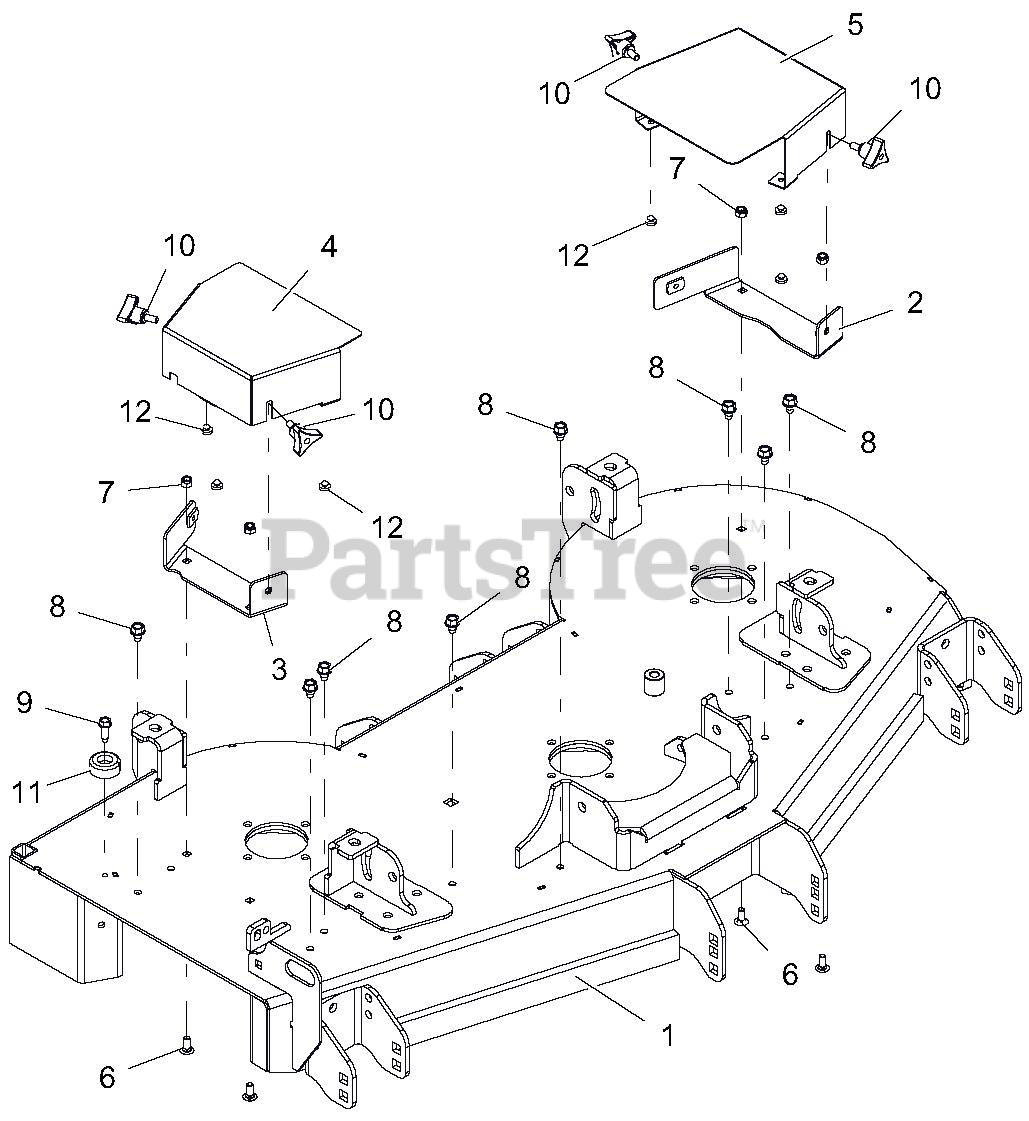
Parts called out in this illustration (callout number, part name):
1	KIT, 48 IN PROSTANCE MOWER DECK W/SAFETY DECALS
2	WLDMT, RH BRKT BELT GUARD MOUNTING
3	WLDMT, LH BRKT BELT GUARD MOUNTING
4	GUARD, RH DECK BELT
5	GUARD, LH DECK BELT
6	BLT-RDHDSQNK .31-18X.75 G5 YWZC
7	NUT-LK-NYL .312-18 YWZC
8	SCR-TAP .38-16X.50 HWH TR YWZ
9	SCR-TAP .31-18X1.00 HWH TR YZ
10	KNOB, WING STUD .312-18X.75
11	BUMPER, RECESSED 1.50 X .63 W/.31 HOLE
12	BUMPER GROMMET .125 X .25 REV
